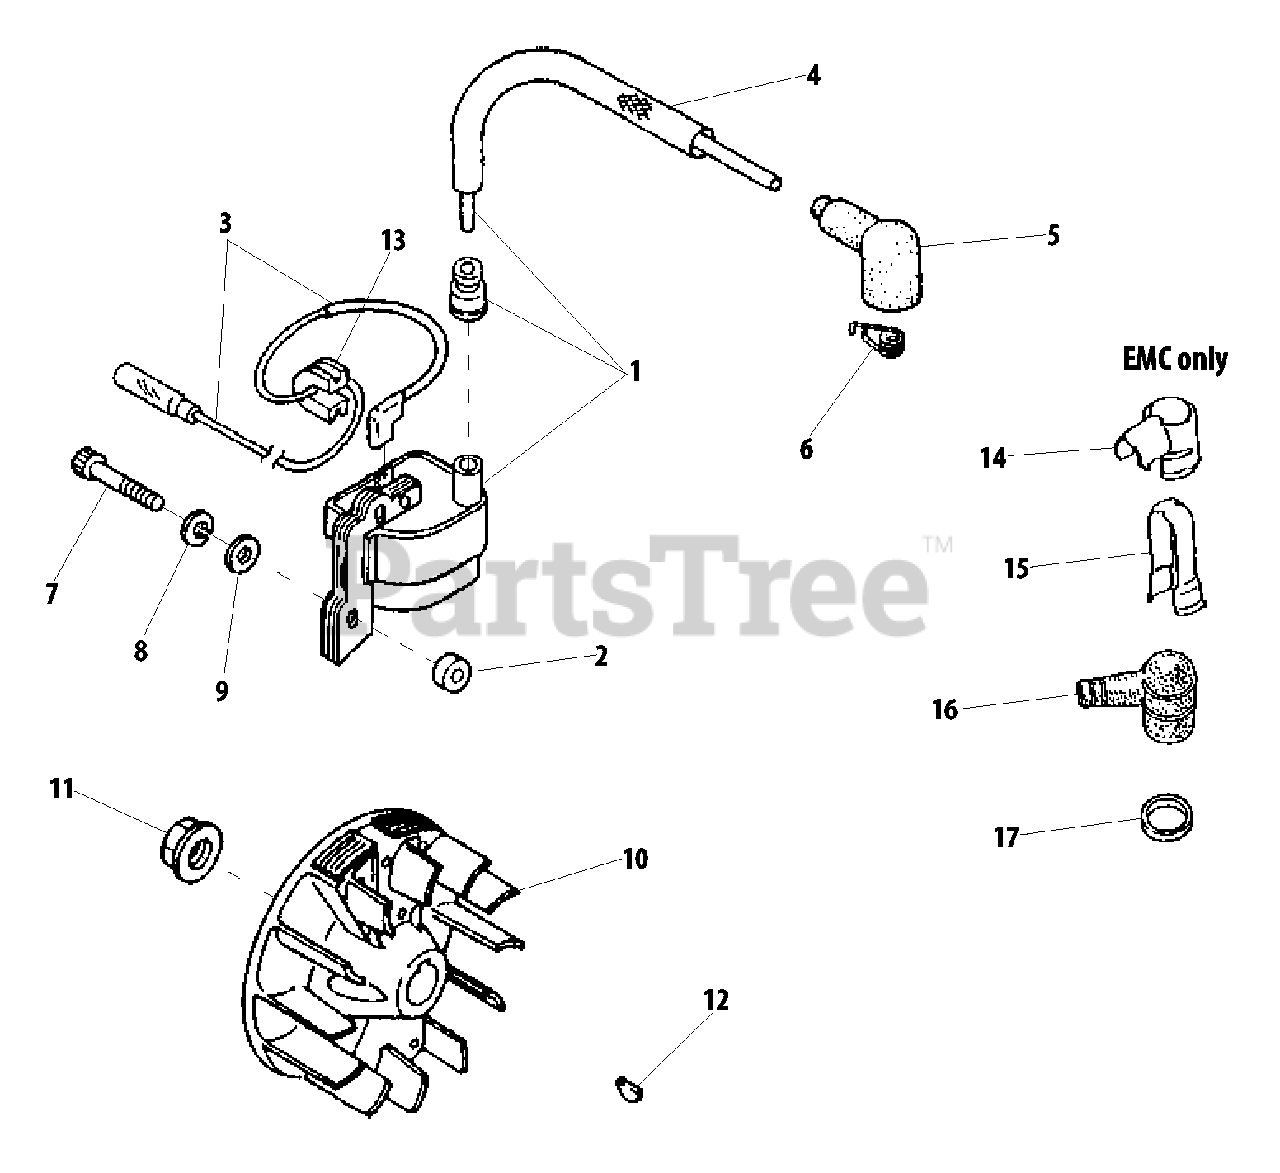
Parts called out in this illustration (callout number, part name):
1	IGNITION COIL ASSY
2	INSULATOR
4	TUBE
5	CAP, SPARK PLUG
6	TERMINAL, SPARK PLUG CAP
7	SCREW - 4X26
8	LOCKWASHER - 4
9	WASHER - 4
10	FLYWHEEL
11	NUT - 8
12	KEY - 3X10
13	GROMMET
14	CAP, SPARK PLUG
15	SHIELD
16	CAP, SPARK PLUG
17	SEAL, DUST
